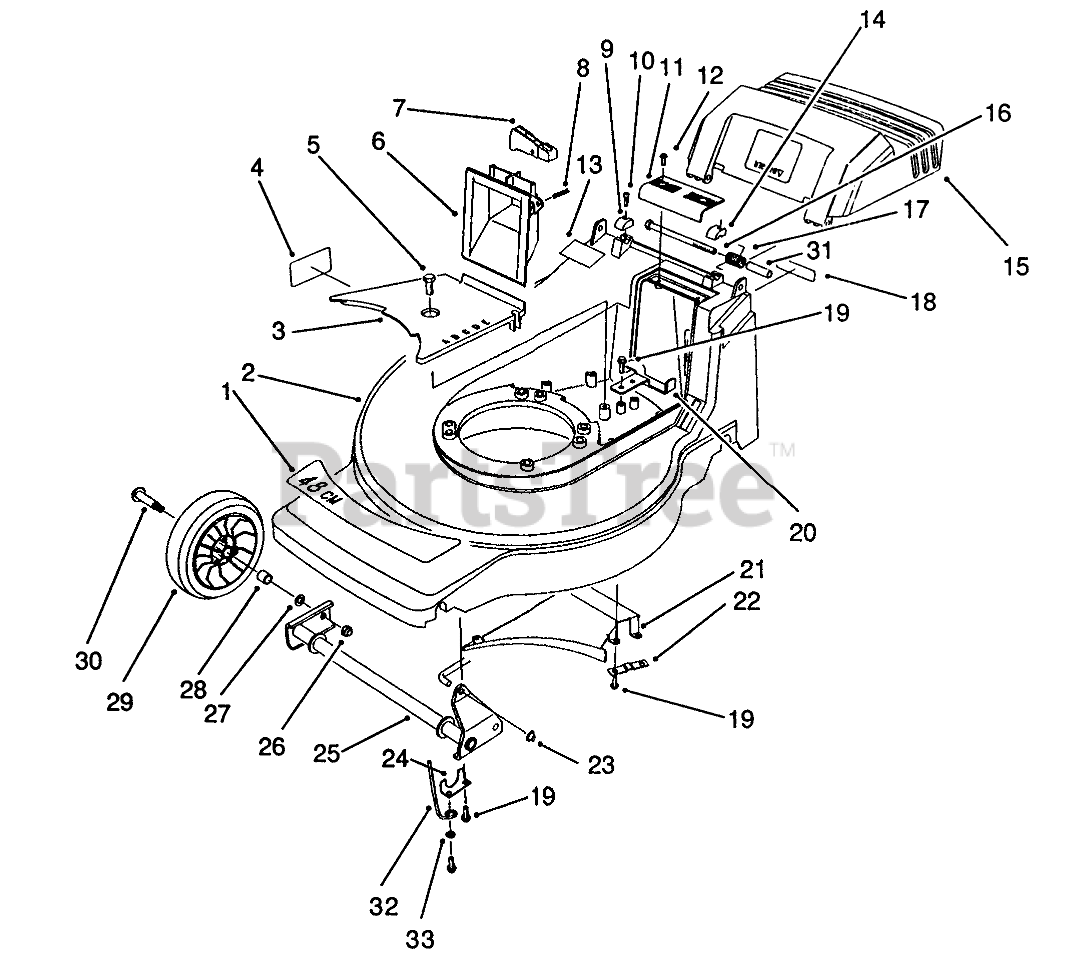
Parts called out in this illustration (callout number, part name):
1	DECAL - DECK
2	Housing-48cm
3	BELT COVER
4	Decal Danger
5	SCREW-HWHTF
6	GRIP - LOWER
7	TRIGGER - HOC
8	PIN-SPIRAL
9	CAP-HINGE BOLT, RH
10	SCREW-HSH
11	GRIP-UPPER
12	SCREW-PPH, PLASTITE
13	Decal-Noise
14	CAP-HINGE BOLT, LH
15	Door-Discharge
16	SCREW-HH
17	DOOR SPRING
18	DECAL FRENCH REGUL.
19	SCREW-HWHTF
20	REAR BELT GUIDE
21	Ramp-Discharge
22	Strap-Rear Suspension
23	NUT-PUSH
24	FRONT SECURING PLATE
25	FRONT PIVOT WA
26	Nut
27	WASHER
28	BUSHING
29	Wheel & Tire Assembly (Incl. Ref. #28)
30	BOLT-WHEEL
31	SPACER-DOOR
32	LH AXLE RETAINER
33	WASHER-FLAT
